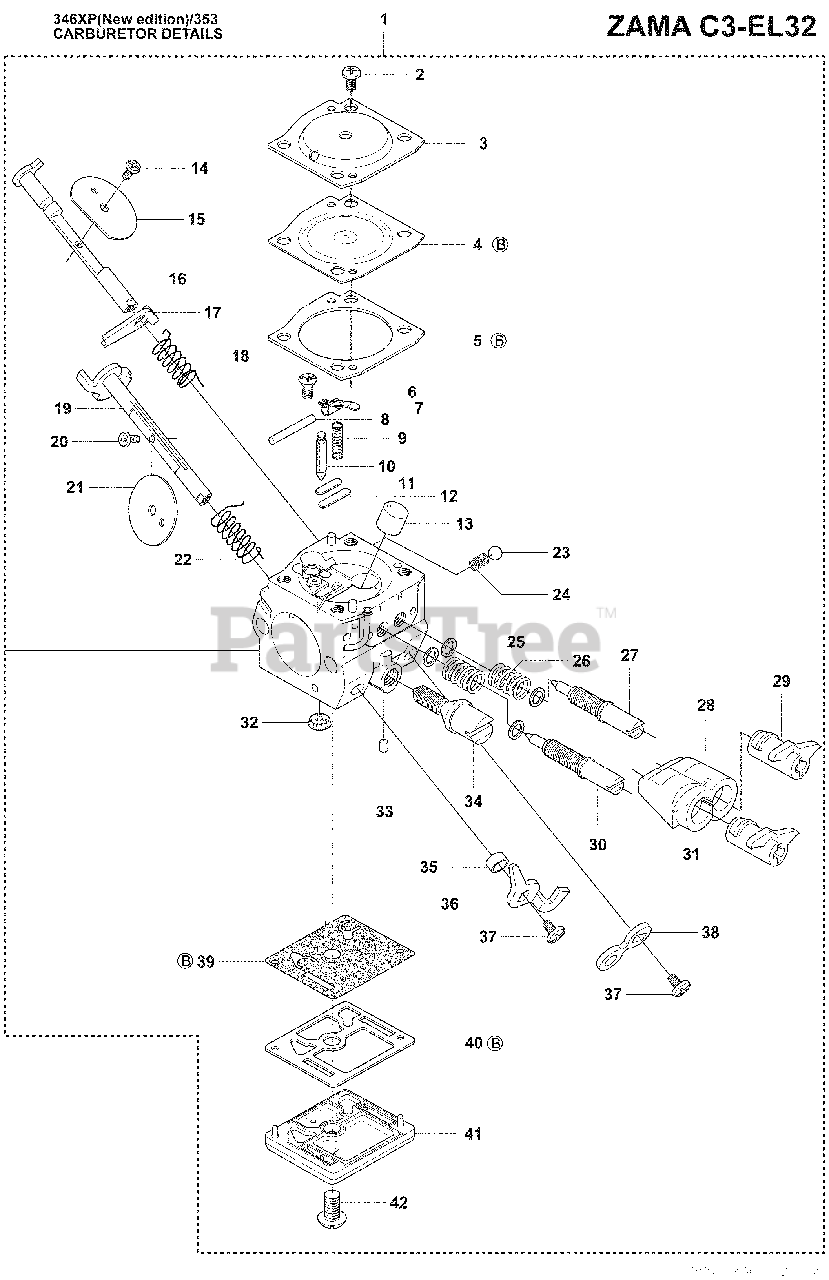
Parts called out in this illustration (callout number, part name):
1	Carburetor
8	Pin
15	CHOKE FLAP
16	Choke Shaft
17	THROTTLE LOCK
19	Throttle Shaft
21	THROTTLE FLAP
26	Spring
29	LIMITER CAP
30	LOW SPEED NEEDLE
31	LIMITER CAP
34	Idle Screw
39	Pump Diaphragm
43	Gasket Set
